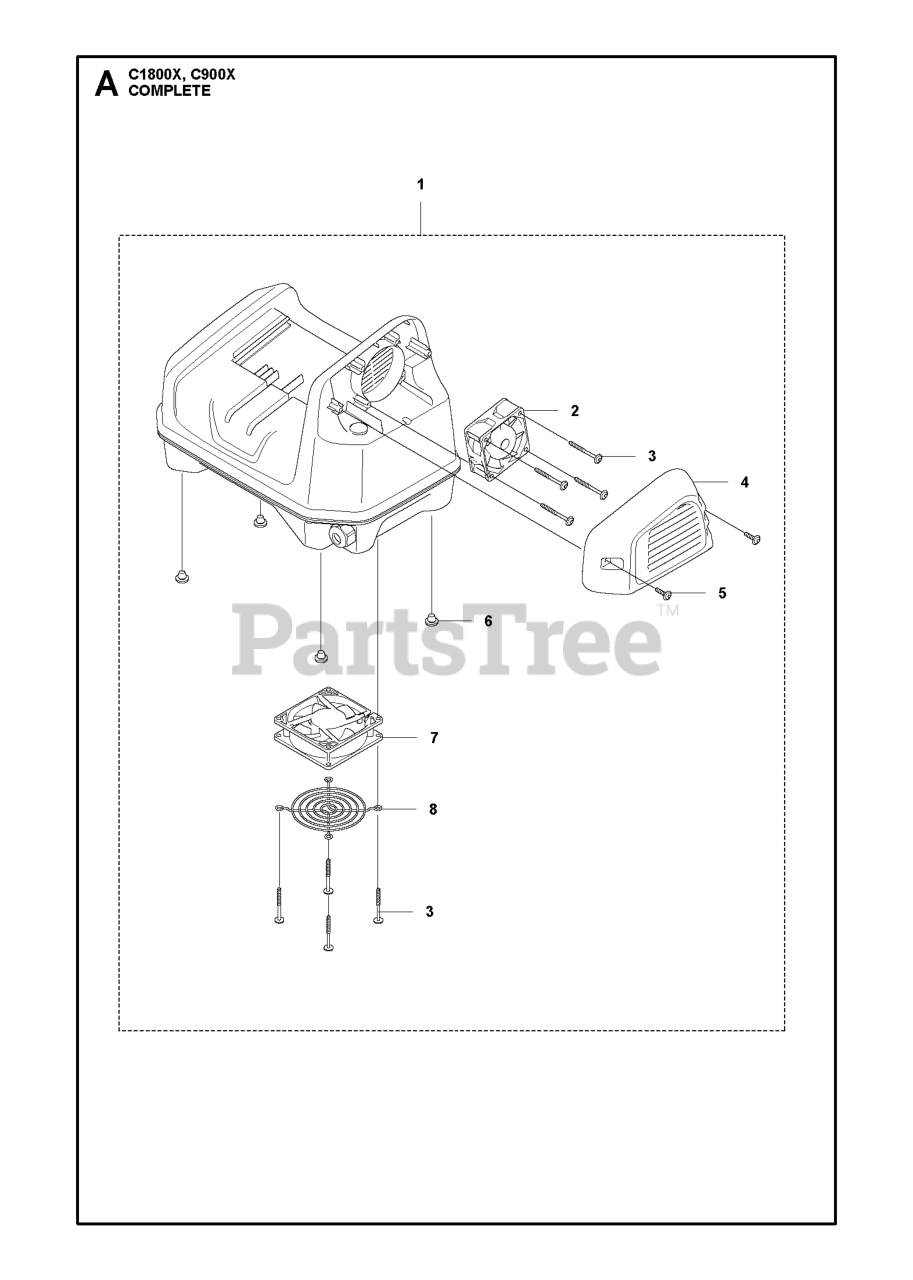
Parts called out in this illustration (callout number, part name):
3	SCREW
5	SCREW ITXSCT PW4.2X18 10.9 ZN
6	RUBBER STOP KIT
8	FAN PROTECTION
